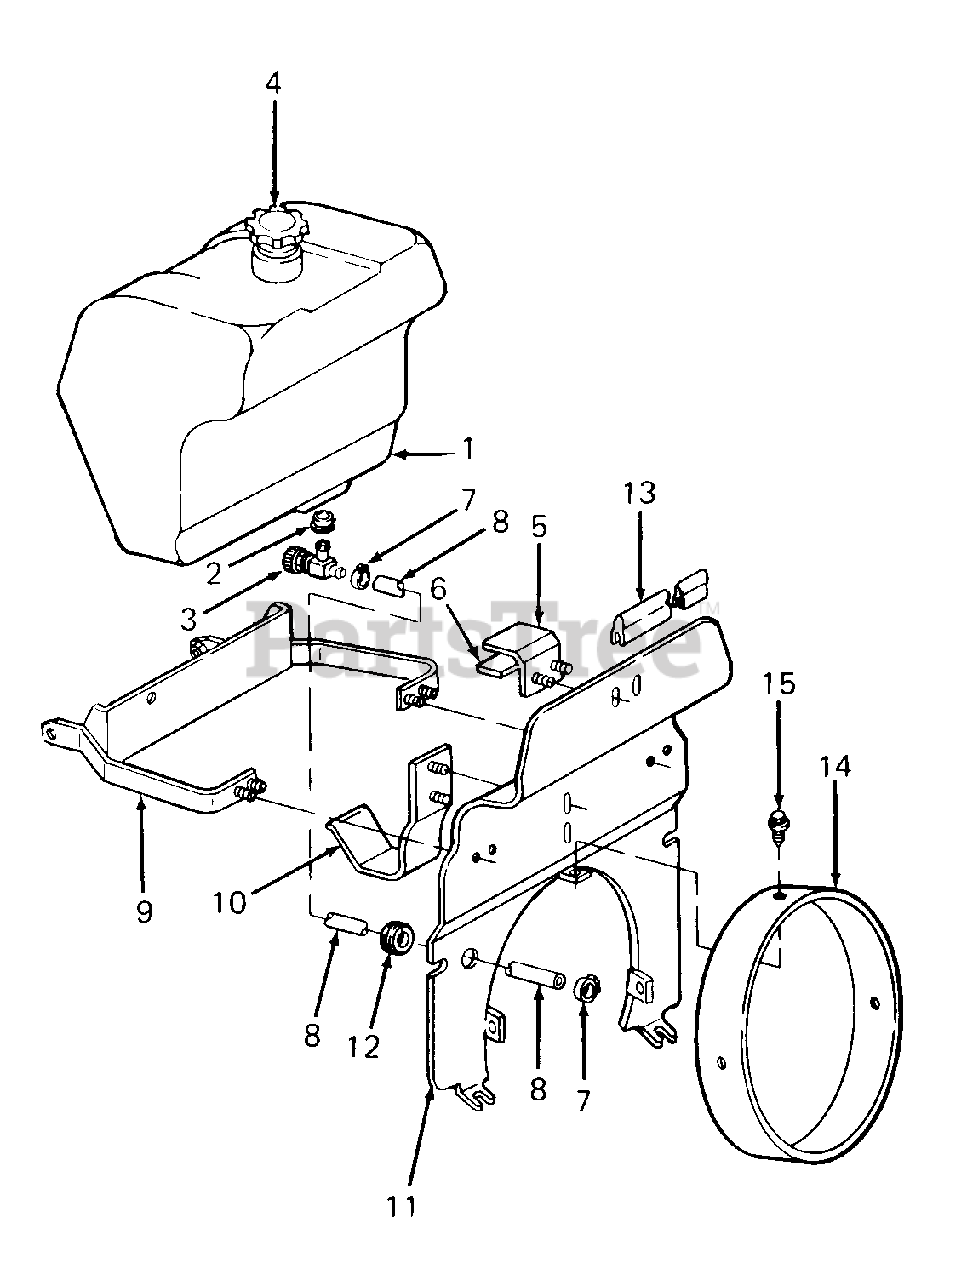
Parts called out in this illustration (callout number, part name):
1	Tank, Fuel
2	Bushing
3	Valve, Shutoff w/Screen
4	Gauge, Fuel Cap
5	Clamp, Fuel Tank
6	Pad, Fuel Tank Adhesive, Loctite #495
7	Clamp, Hose
8	Line, Fuel-14 in. Lg
9	Support, Fuel Tank
10	Support, Fuel Tank Bottom
11	Deflector, Heat
13	Seal, Heat Baffle, 56 in Lg
14	Shroud, Blower
15	Screw, Hex Wash Hd AB Tapp, #10 X .50 Lg
